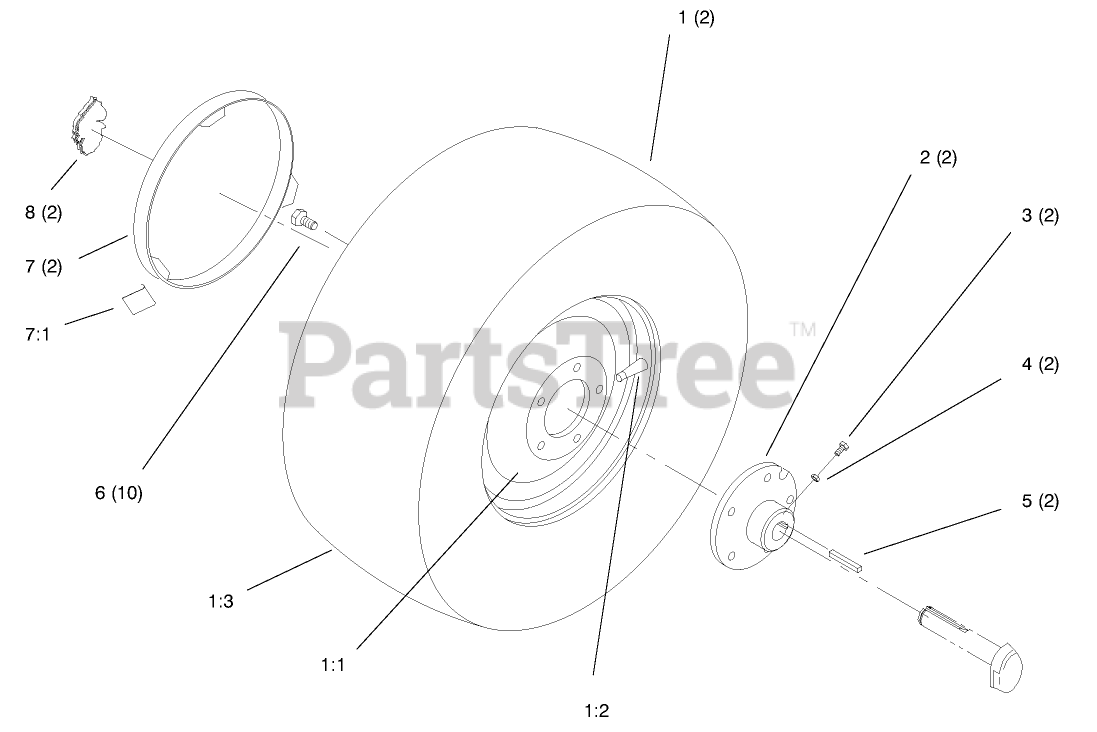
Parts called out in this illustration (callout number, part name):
1	Wheel Tire ASM Rear
1:1	WHEEL
1:2	VALVE
2	HUB-WHEEL
3	SCREW-SET, SQH
4	NUT-JAM
5	KEY-SQUARE
6	BOLT-LUG
